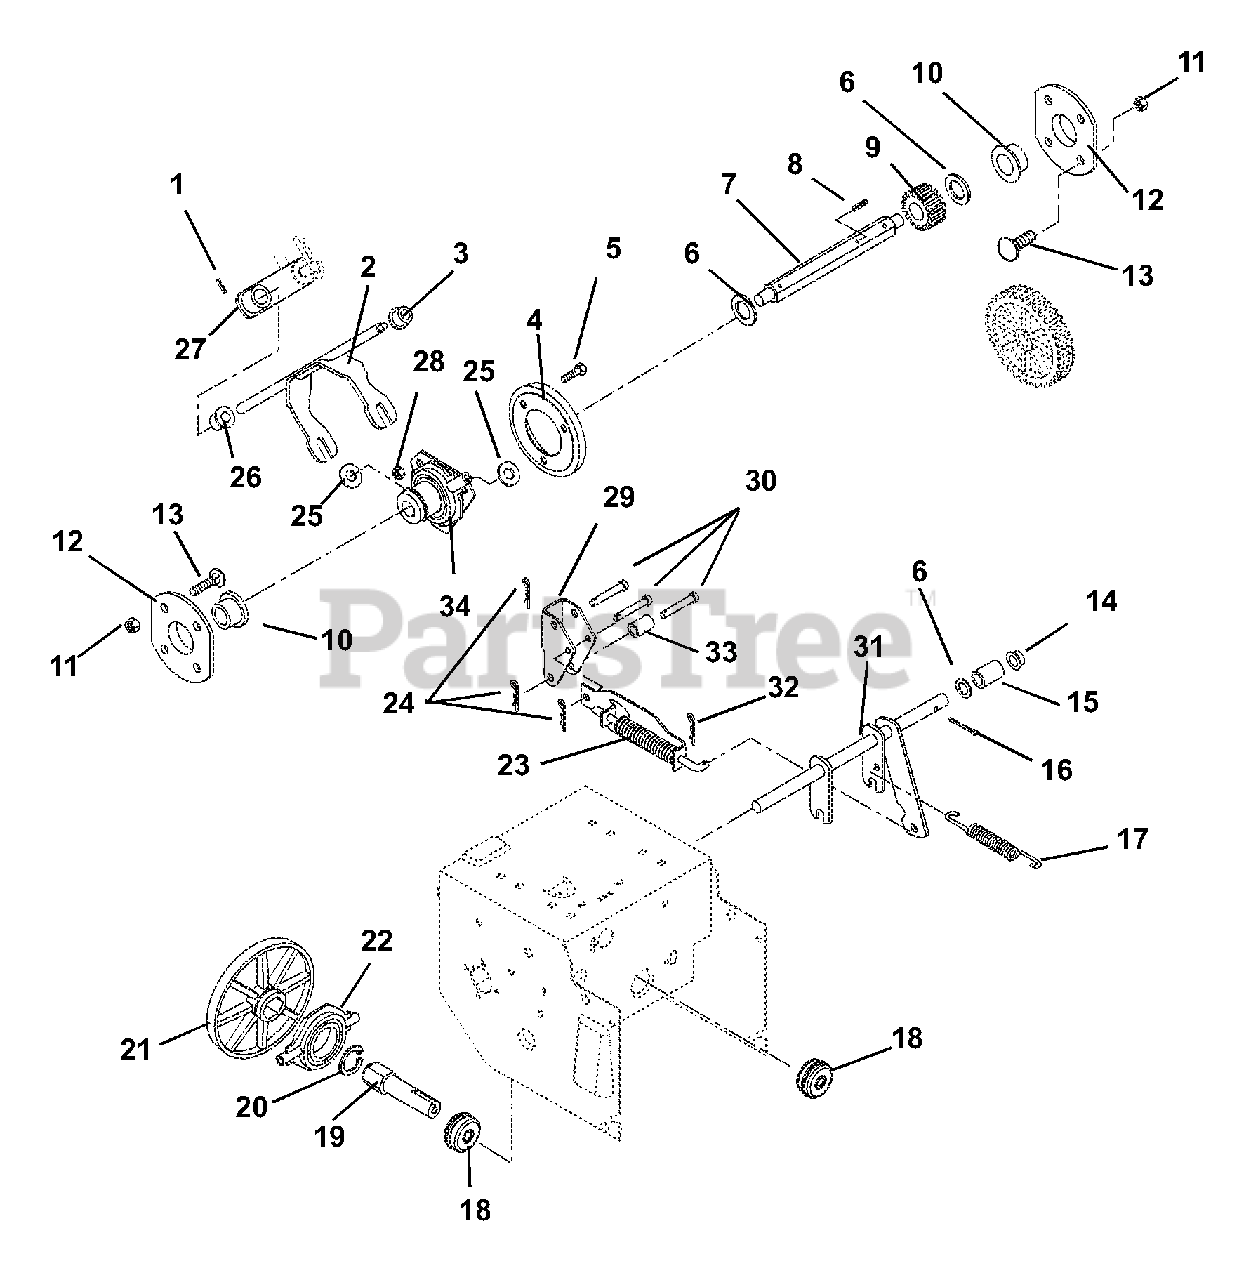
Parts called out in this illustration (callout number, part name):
1	PIN-ROLL .156X.88
2	FORK-SPEED
3	BSHG-FLG .325X.444X.440X.560
4	DISC, FRICTION - 730 MAT'L
5	@BLT-HEX .25-20X.50 GR5 YWZC
6	@WSHR-FL-STL.531X1.06X.095YWZC
7	HEX SHAFT
8	PIN-ROLL .125X.88
10	BSHG-FLG .500X.750X.625X.937
11	NUT-LK-DUAL FACE 10-24 YWZC
12	FLANGE AND BUSHING
13	BLT-RDHDSQSHK #10-24X.38 GR2YW
14	CAP, .50 ROD YWZC
15	SPACER .504X.748X.321
16	@PIN-CTR .12X1.00 EXTPRSQCT YZ
17	SG-TENS .063X.44X1.56
18	BRG-BALL,.625X1.38X.43 SNAP RG
19	SPINDLE SHAFT, 932 DRIVE PLATE
20	RG-RTNG-EXT 1.250X.050
21	FRICTION PLATE
22	BEARING ASSEMBLY
23	TRACTION CLUTCH ASSY
24	PIN-HAIR INT .06X.18X.77
25	WSHR-FL-STL .505X1.00X.062YWZC
26	BSHG-FLG .500X.625X.500X.750
27	ARM, SPEED CONTROL
28	@NUT-LK-CTR .25-20 YWZC
29	BRACKET, TRACTION ARM
30	PIN,CLEVIS .243/.248 X 1.38 YZ
31	CLUTCH FORK
32	PIN-HAIR INT .08X.18X1.18 YWZC
33	SPACER .325 X.625 X.455
34	SHIFT CARRIER
